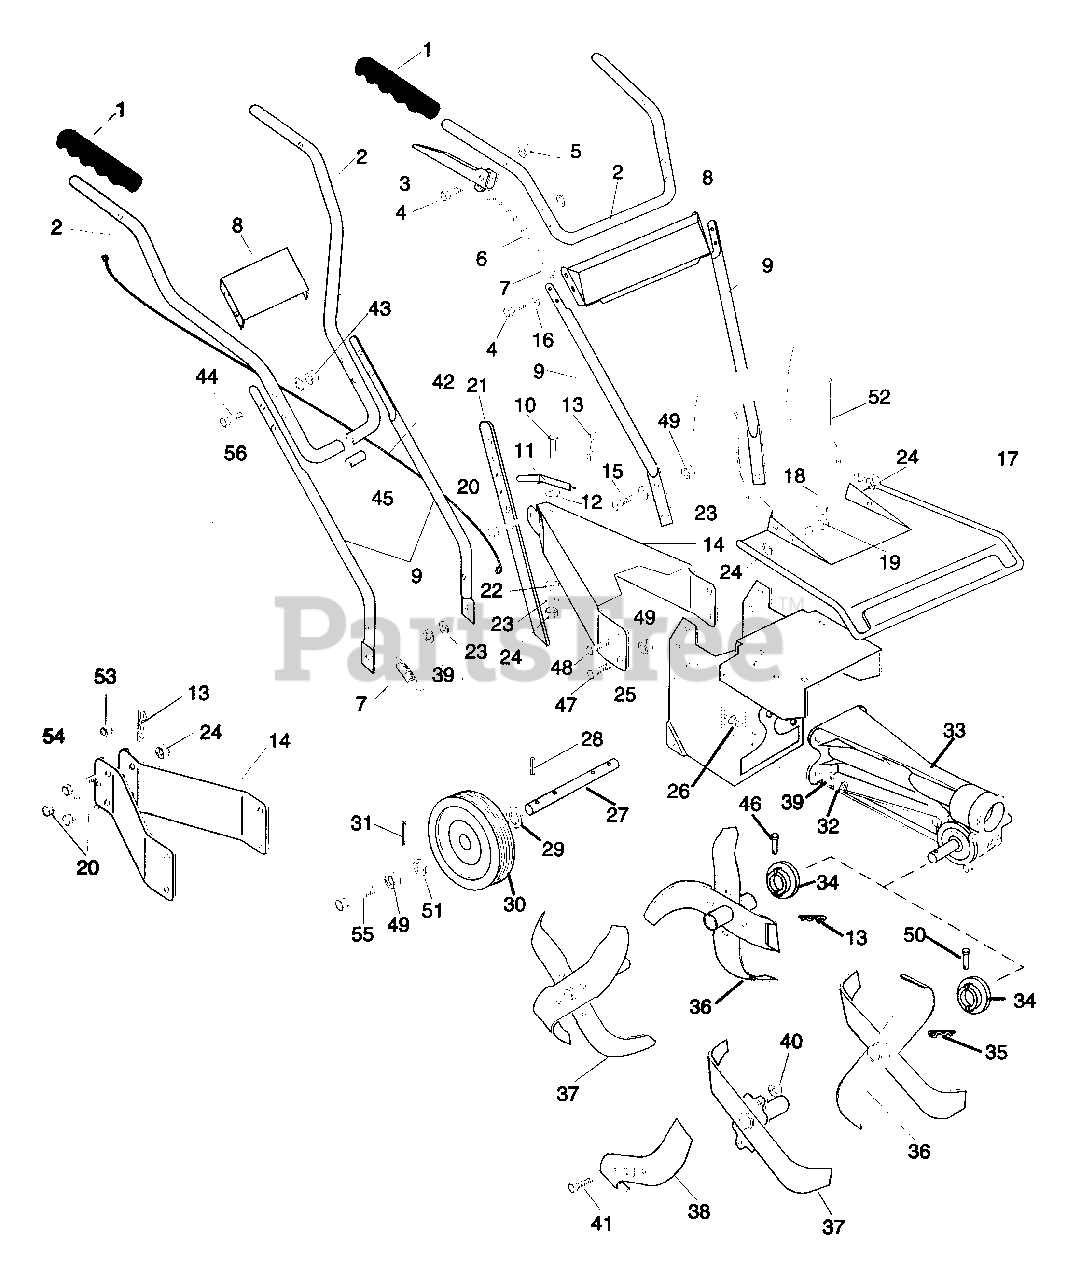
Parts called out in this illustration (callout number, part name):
1	GRIP
1	HANDLE GRIP- BLACK PVC-SM1217
2	RIGHT UPPER HANDLEBAR
2	LEFT UPPER HANDLEBAR
2	HANDLEBAR
3	HANDLE, CLUTCH
4	@BLT-HEX .25-20X1.50 GR5 YWZC
5	@NUT-LK-CTR .25-20 YWZC
6	CLUTCH CHAIN
7	SG-TENS .080X.25X31.6 WLD 35
7	SG-TENS .092X.69X1.75 WLD 54
8	HANDLEBAR PANEL
8	NAME PLATE
9	LOWER HANDLE BAR
9	HANDLEBAR, LOWER
10	@BLT-HEX .38-16X.75 GR5 YWZC
11	RETAINER CLIP
12	WAVE WASHER .515 X 1.00 X .125
13	PIN-HAIR-EXT .12X.31X2.37 YWZC
13	PIN-HAIR INT .08X.18X1.18 YWZC
14	DEPTH STICK HOLDER
15	@BLT-HEX .38-16X1.00 GR5 YWZC
16	@WSHR-FL-STL.281X.62X.065 YWZC
17	TINE HOOD
18	@BLT-RDHDSQNK .31-18X.75 G5YZ
19	@BLT-HEX .31-18X.75 GR5 YWZC
20	CLEVIS PIN .437/.431X1.50 YWZC
20	PIN-CLEV .438X.958 PL
21	DEPTH STICK
22	SPACER BUSHING .5 X .32 X .21
23	@WSHR-FL-STL.38X.875X.083 YWZC
24	@NUT-LK-CTR .31-18 YWZC
25	FRAME
26	@BLT-HEX .38-16X1.25 GR5 YWZC
26	SCREW - FLG WIZ LOCK HH PL
27	AXLE ROD
28	PIN-ROLL .125X1.38
29	SPACER .76 X .51 X .56
30	WHL
30	T/WHL ASSY
31	@PIN-CTR .12X1.25 EXTPRSQCT YZ
32	@NUT-HEX .38-16 YWZC
33	GEAR CASE - CAST IRON
33	GEAR CASE-ALUM-902806,07,08,09
34	DUST CAP
35	PIN-HAIR INT .08X.38X1.42 YWZC
36	RH INNER TINE SPOOL
36	LH INNER TINE SPOOL
36	R.H. INNER TINE SPOOL
36	L.H. INNER TINE SPOOL
37	LH OUTER TINE SPOOL
37	RH OUTER TINE SPOOL
37	R H OUTER TINE SPOOL
37	L H OUTER TINE SPOOL
38	TURBO-TINE
39	@WSHR-LK .38X.094 REG YWZC
40	@NUT-LK-CTR .44-14 YWZC
41	@BLT-HEX .44-14X1.00 GR5 YWZC
42	CLUTCH CABLE FORWARD
43	@NUT-HEX .31-18 YWZC
44	BLT-CRVD-HD .31-18X1.44 YWZC
45	HANDLEBAR INSERT
46	PIN, CLEVIS .243/.248X1.50 YWZ
47	@BLT-HEX .38-16X.75 GR5 YWZC
48	BLT-HEX .38-16X1.50 PL GR5
49	@NUT-LK-CTR .38-16 YWZC
50	CLEVIS PIN
51	@WSHR-FL-STL.531X1.06X.095YWZC
53	SPACER .333X.520X.340
54	@BLT-HEX .31-18X1.00 GR5 YWZC
55	SHOULDER BOLT .50 X 1.51 YWZC
56	@WSHR-LK .31X.078 REG YWZC
